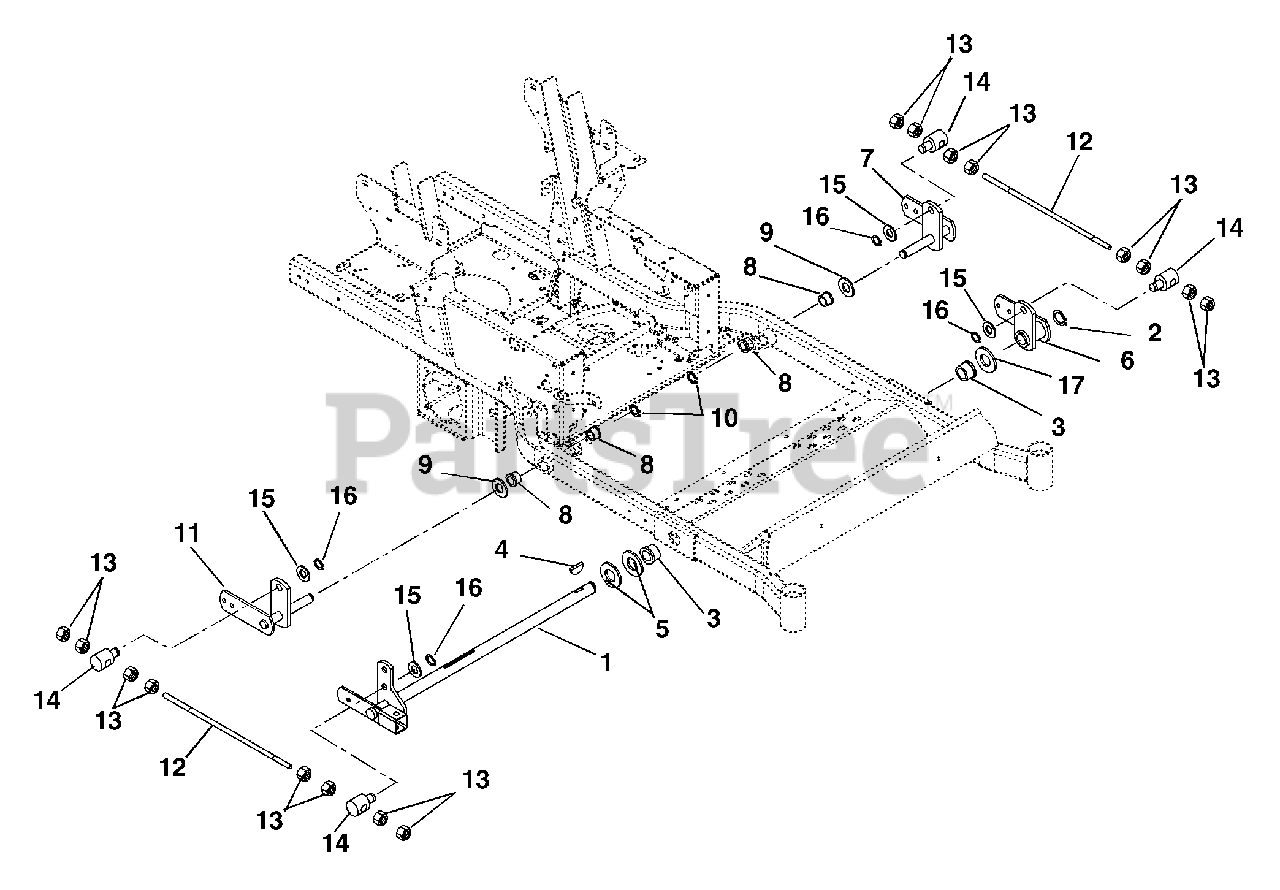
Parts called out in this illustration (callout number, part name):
1	Weldment, Lift Arm
2	Ring-Retaining-External 1.00 x .078
3	Bushing-Flange-Nylon 1.020 x 1.385 x .75 x 1.75
4	Key-Woodruff .25 x 1.00
5	Washer-Flat-Steel 1.063 x 2.00 x .134
6	Weldment, Lift Arm-Front
7	Weldment, Lift Arm-Shaft-Left Hand
8	Bushing-Flange-Nylon .762 x 1.0 x .580 x 1.48
9	Washer-Hardened-Steel .758 x 1.23 x .031
10	Ring-Retaining-External .689 x .077
11	Weldment, Lift Arm Shaft-Right Hand
12	Rod-Lift Assist
13	Nut-Jam .50-13
14	Pivot-Mower Lift
15	Washer-Flat-Steel .630 x 1.005 x .062
16	Ring-Retaining-External .625 x .05
17	Washer-Hardened-Thrust 1.00 x 1.55 x .03
